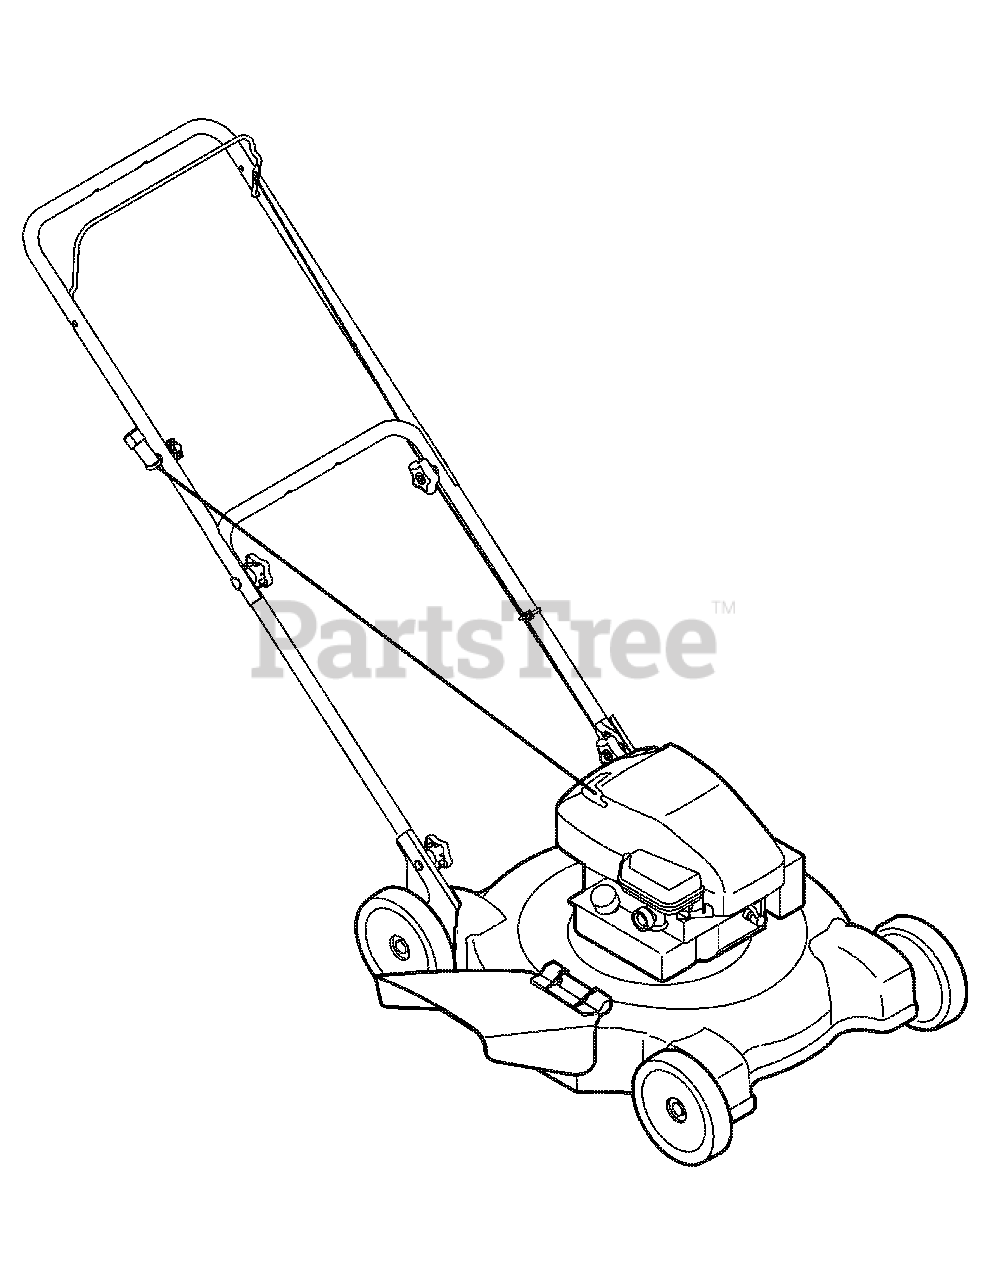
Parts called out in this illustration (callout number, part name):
NA	Pre-Filter
NA	Drive Belt
NA	Drive Cable
NA	Ignition Key
NA	Grass Bag
